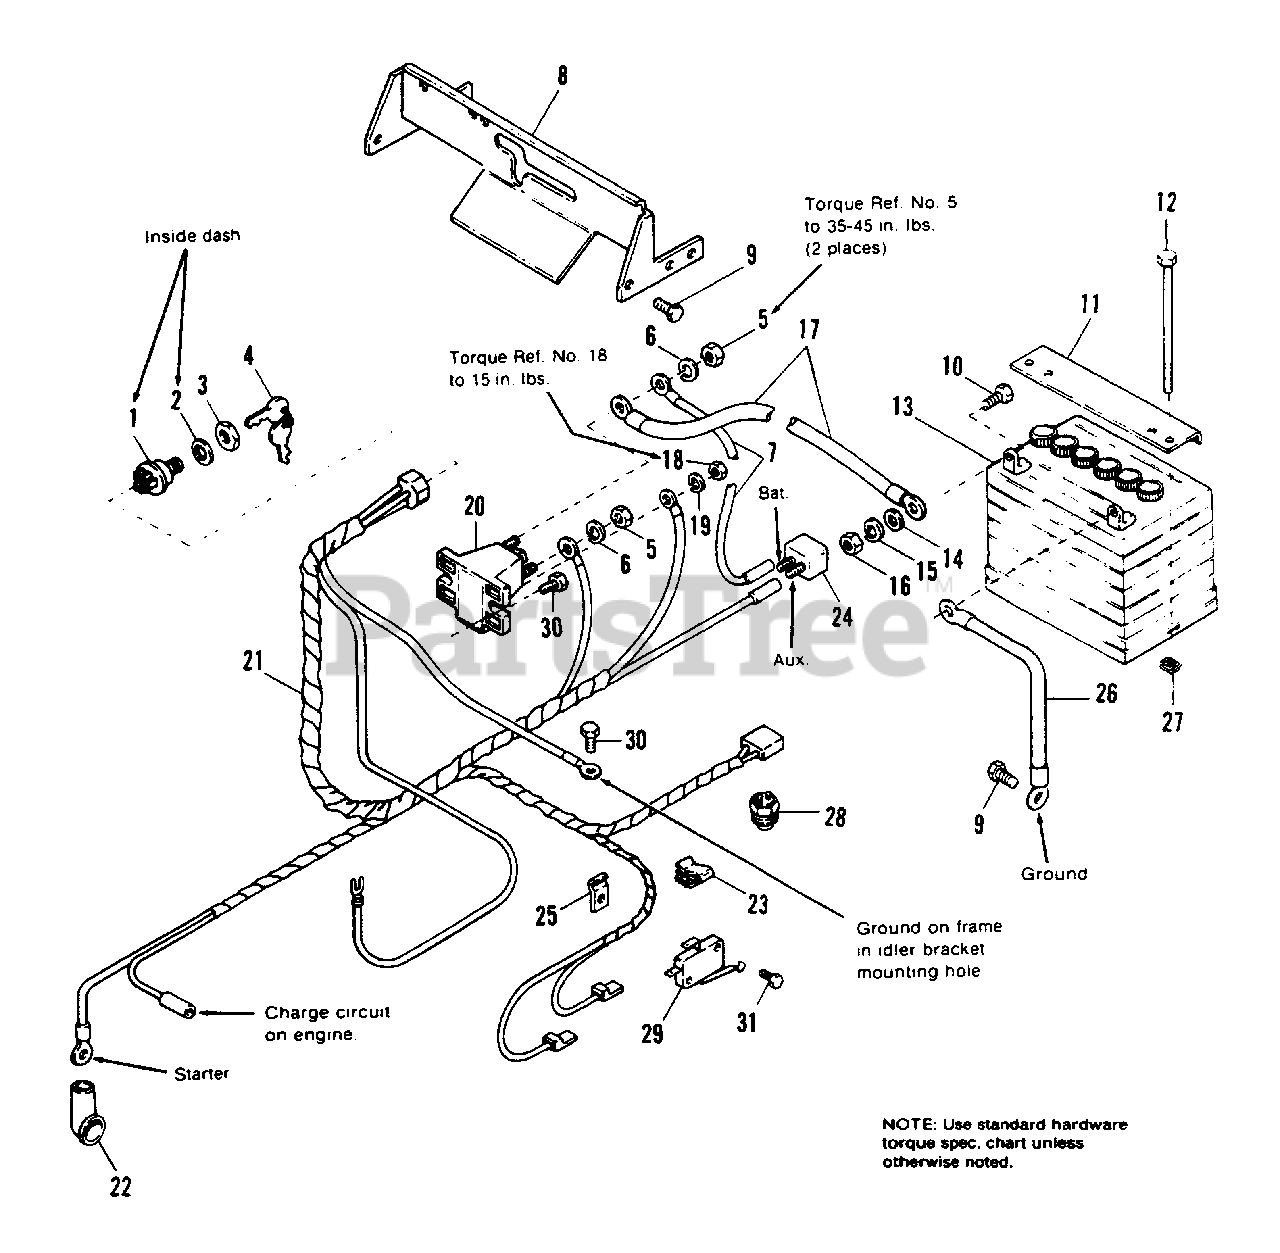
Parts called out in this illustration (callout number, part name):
1	SWITCH, Ignition
2	LOCKWASHER, Internal Tooth, 5/8
3	NUT, 5/8-32
5	NUT, Hex, 5/16-18
6	LOCKWASHER, 5/16
8	QUADRANT, Shift
9	SCREW, Taptite, 1/4-20 x 3/8
10	CAPSCREW, Hex, 1/4-20 x 3/4
11	CLAMP, Battery
12	CAPSCREW, Hex, 1/4-20 x 7
13	BATTERY SERVICE KIT
14	WASHER, 1/4
15	LOCKWASHER, 1/4
16	NUT, Hex, 1/4-20
18	NUT, Hex, #10-32
19	LOCKWASHER, Ext., #10
20	SOLENOID
21	HARNESS, Wiring
22	COVER, Terminal
23	CLIP, Speed
24	CIRCUIT BREAKER
27	NUT, Retainer, 1/4-20
28	SWITCH, PTO
29	SWITCH, Interlock
30	SCREW, Taptite, 1/4-20 x 3/4
31	SCREW, Taptite, #5-40 x 3/4
